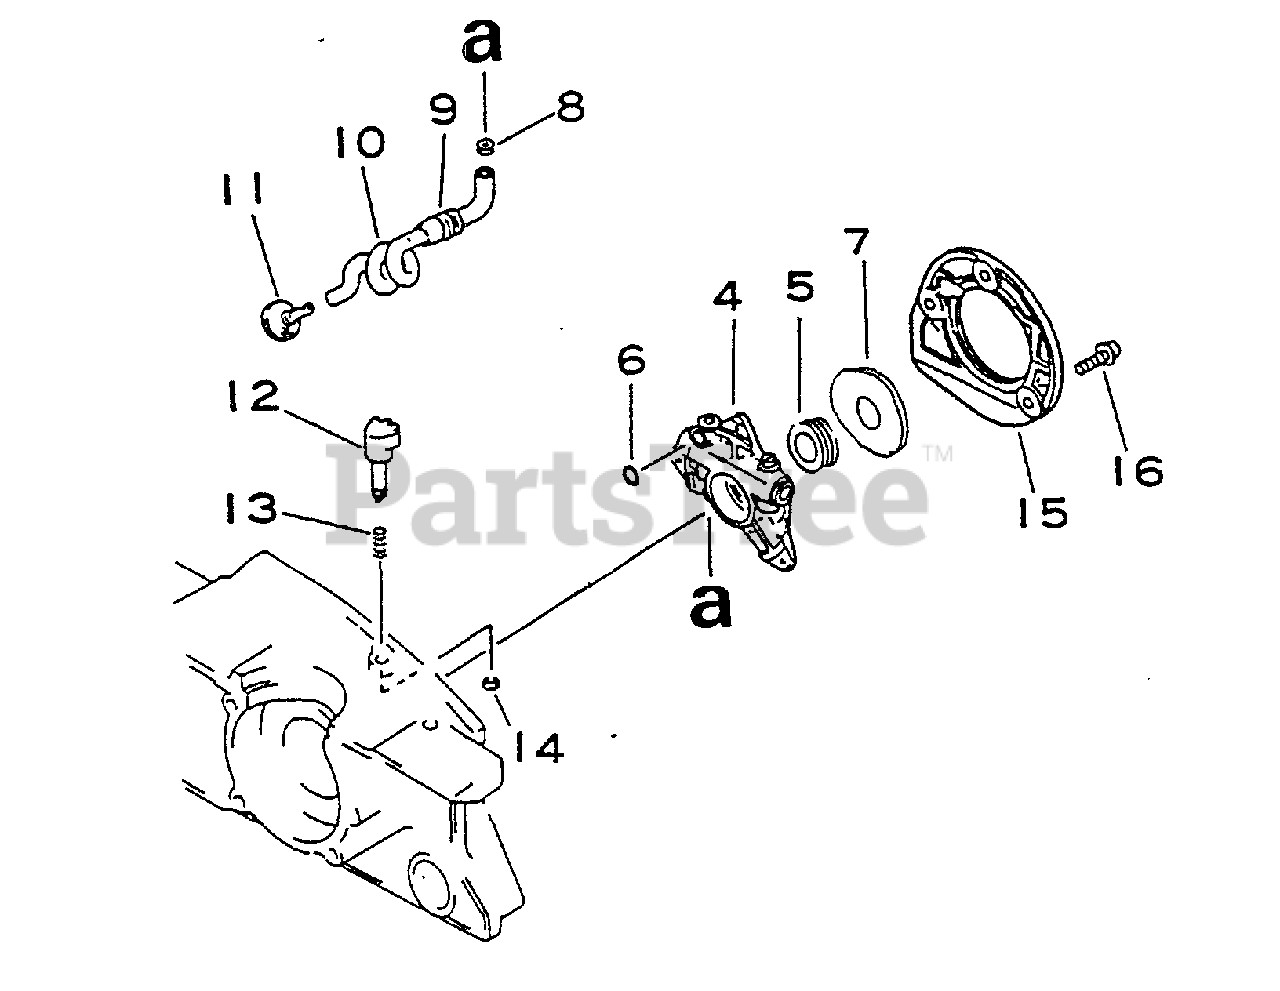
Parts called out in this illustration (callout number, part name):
4	AUTO-OILER ASSY
5	GEAR - WORM
6	O-RING - 3
7	COVER
8	CLIP - 6.5
10	PIPE, OIL - SPIRAL
11	FILTER, OIL
12	DIAL, AUTO-OILER
14	RING, RETAINING - 3
15	COVER, OIL PUMP
16	SCREW - 4X14
